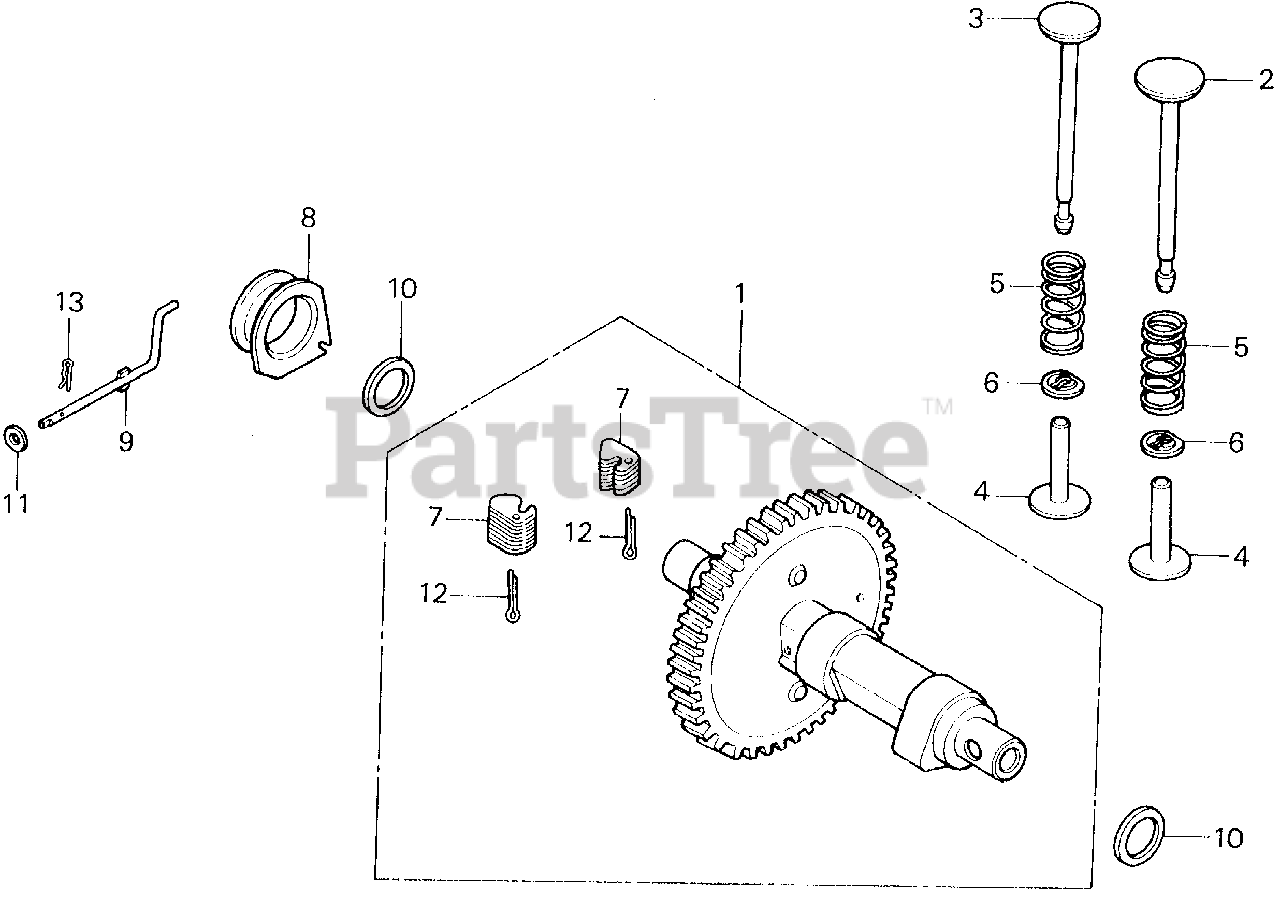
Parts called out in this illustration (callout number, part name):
1	CAMSHAFT ASSY.
2	VALVE, IN.
3	VALVE, EX.
4	LIFTER, VALVE (34.39)
4	LIFTER, VALVE (34.66)
5	SPRING, VALVE
6	RETAINER, VALVE SPRING
7	WEIGHT, GOVERNOR
8	SLIDER, GOVERNOR
9	SHAFT, GOVERNOR ARM
10	WASHER, THRUST (18MM)
11	WASHER, PLAIN (5MM)
12	PIN, COTTER (3.0X45)
13	PIN, LOCK (8MM)
